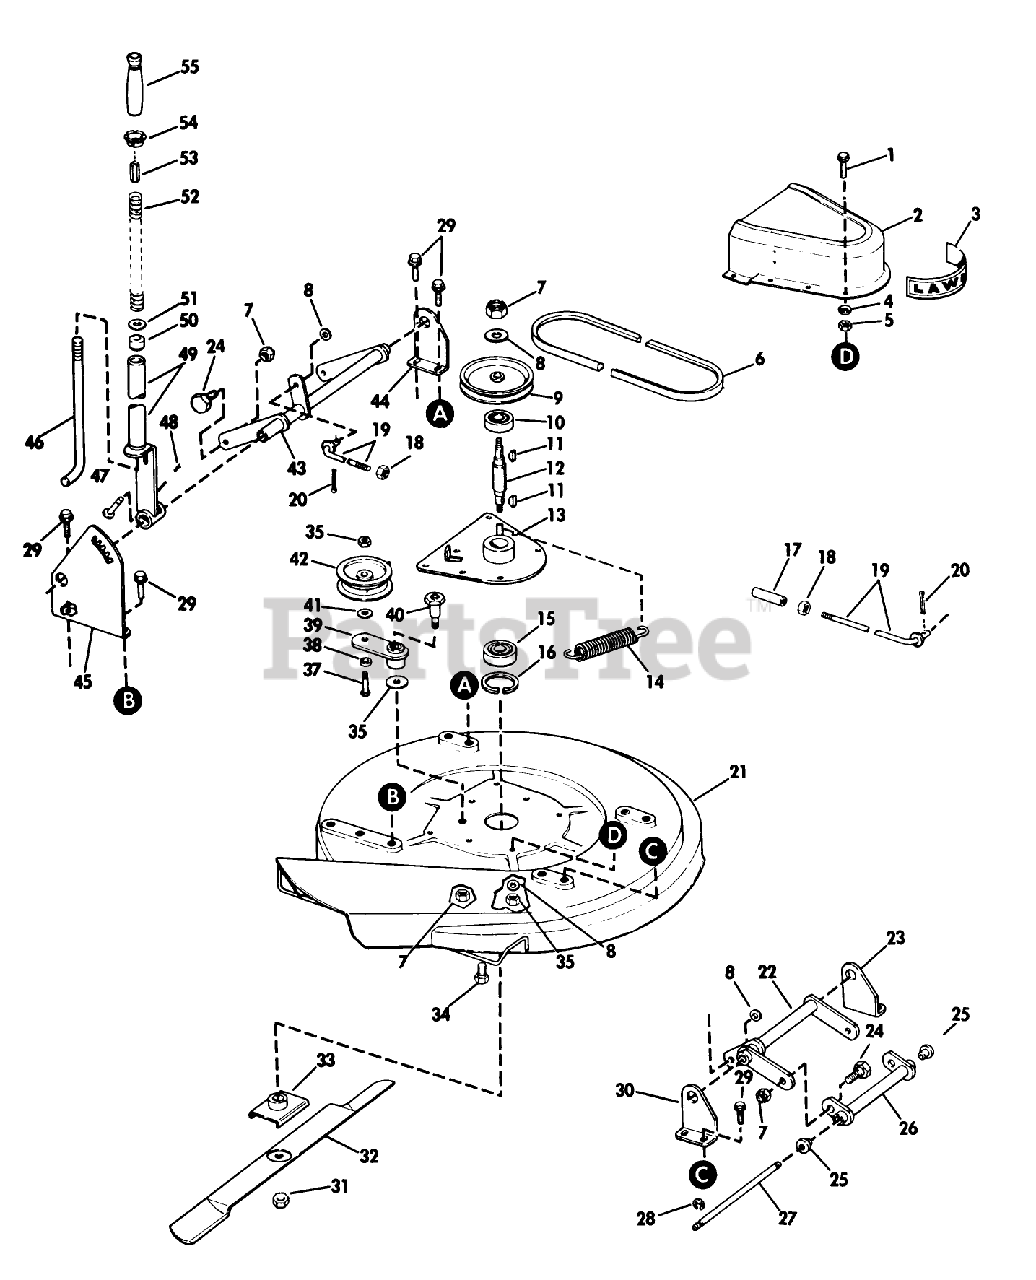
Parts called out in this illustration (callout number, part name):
3	Decal-LAWN-BOY BELT COVER
4	Lockwasher
5	Plug-Core
18	Jam Nut-Stabilizer Link Assembly
35	LOCKNUT
53	Button-Release
